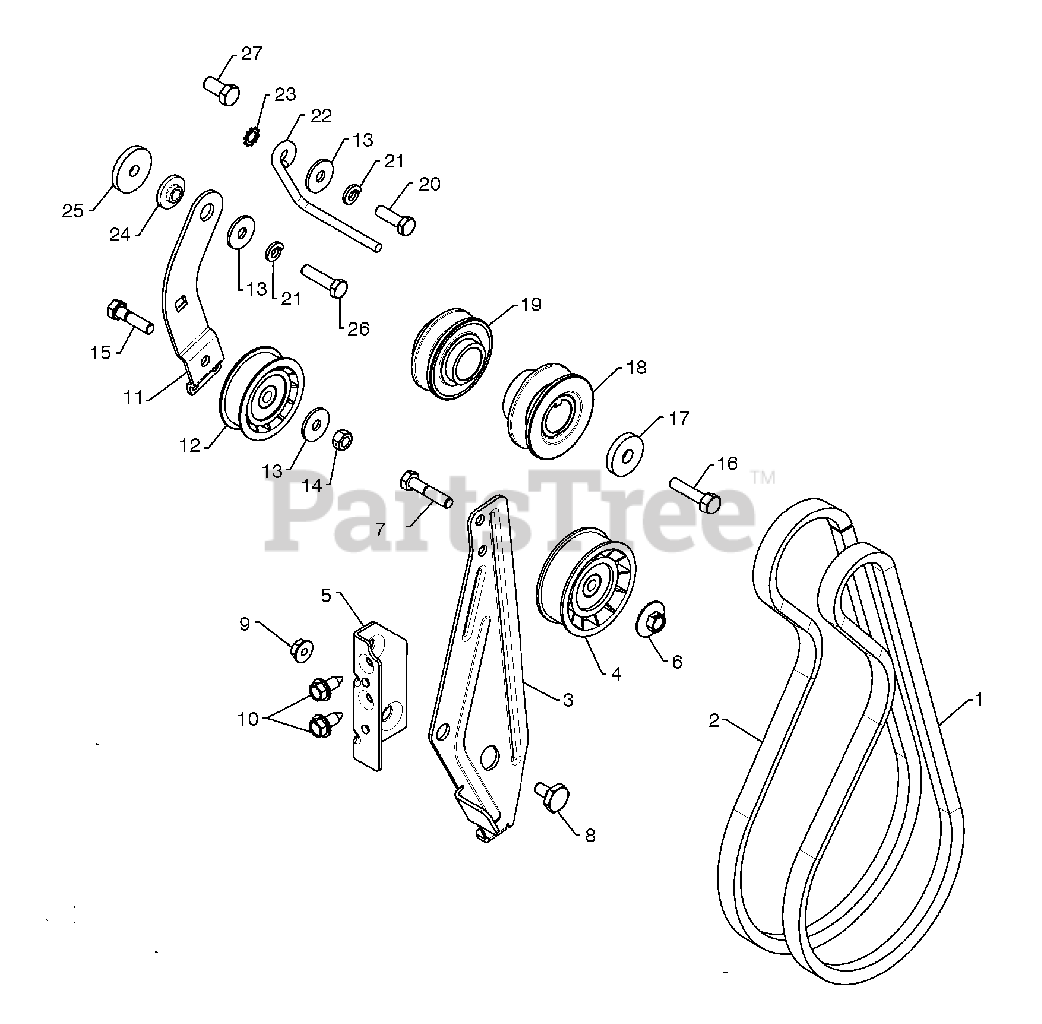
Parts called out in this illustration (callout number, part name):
1	V-BELT.IMPELLER
2	TRACTION BELT
3	ARM.IDLER.BRAKE.
4	PULLEY.W/SPACER.2.75
5	RP BRACKET.IDLER.PIVOT
6	NUT.FLANGE.HEX.5/16X18.BLACK
7	HEX BOLT
8	BOLT.SHOULDER.1/2X12
9	NUT.LOCK.5/16-18
10	BOLT.HEX.HD.WASHER.5/16-18X.75
11	RP ARM.ASM.TRACTION.IDLER
12	PULLEY.W/SPACER.2.25
13	STEEL WASHER
14	NUT.71038.31-18.HEX.NYLOCK
15	BOLT.5/16-18X1-1/4 FULL.THREAD
16	SCREW, HEX HD 3/8-24 X 1-3/8
17	WASHER.400X1.25X5.
18	PULLEY ENG IMPELLER
19	PULLEY.ASM.ENG.TRACTION.1.00
21	WASHER.LOCK.HVY.HLCL.SPR.5/16
22	BELT.GUIDE.RH
23	WASHER EXT TOOTH LOCK 5/16
24	RP BUSHING, IDLER PIVOT
25	WASHER.FLAT.34X1.38X22
26	CAPSCREW.HEXHD.5/16X1.25.
27	SCREW.3/8-16 X .750 (2 2)
